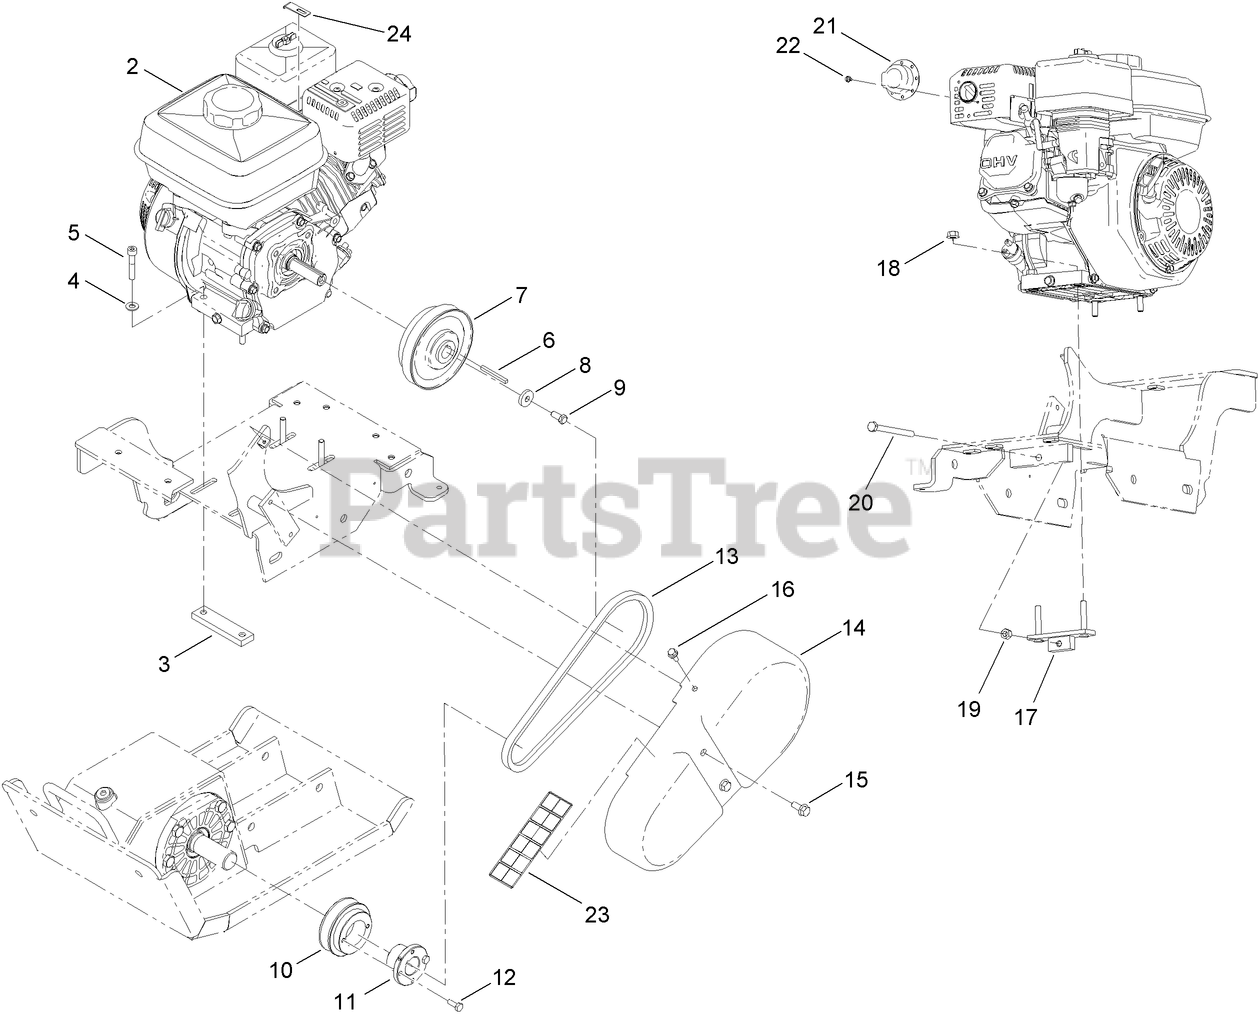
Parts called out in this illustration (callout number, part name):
2	ENGINE-HONDA, GX120
3	PLATE-NUT, ENGINE
4	WASHER-PLAIN
5	SCREW-HSH
6	KEY-SQUARE
7	CLUTCH, S-PLATE
8	WASHER
9	SCREW-HH
10	SHEAVE
11	BUSHING
12	SCREW-HSBH
13	BELT-V
14	GUARD-BELT
15	SCREW-HHF
16	SCREW-HHF
17	BRACKET-ADJUSTER, ENGINE
18	NUT-HF
19	NUT-HEX
20	SCREW
21	DEFLECTOR
22	SCREW-PPHTF
23	DECAL-WARNING, PLATE
24	CLIP-THROTTLE
